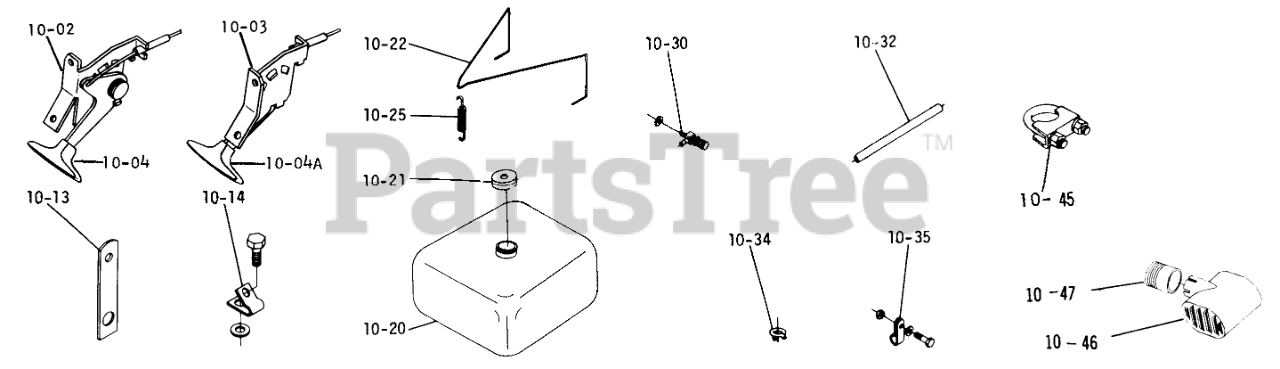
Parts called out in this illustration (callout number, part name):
10-02	Choke Control
10-03	THROTTLE CONTROL
10-04	KNOB-CHOKE
10-04A	KNOB-THROTTLE
10-13	Strap
10-14	THROTTLE CONTROL CLP
10-20	ASSY-FUEL TANK
10-21	Cap
10-22	HOLD DOWN WIRE
10-25	CLUTCH SPRING
10-30	VALVE-FUEL
10-32	Hose-Fuel
10-34	Clamp
10-35	CLAMP-HOSE
10-45	ASSY-MUFFLER CLAMP
10-46	MUFFLER
10-47	Nipple
